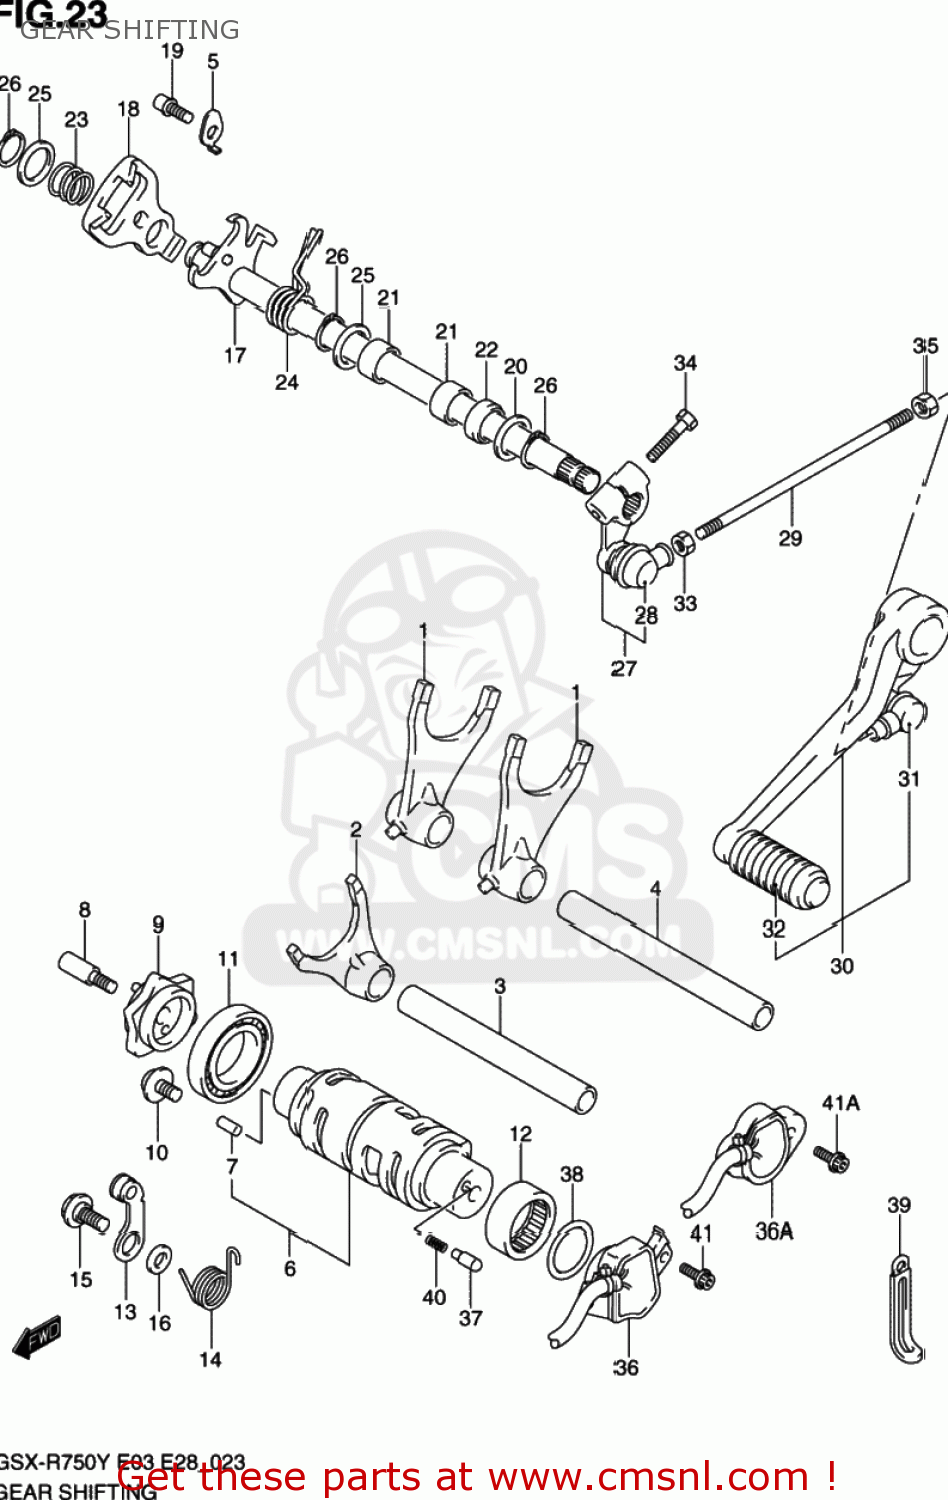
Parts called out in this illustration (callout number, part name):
1	FORK,GEAR SHIFT NO.1
2	FORK,GEAR SHIFT NO.3
3	SHAFT,GEAR SHIFT FORK
4	SHAFT,GEAR SHIFT FORK NO.1
5	RETAINER,GEAR SHIFT FORK SHAFT
6	CAM,GEAR SHIFT
7	PIN
8	BOLT,GEAR SHIFT CAM PL
9	PLATE,GEAR SHIFT CAM
10	SCREW(6X12)
11	BEARING(25X47X8)
12	BEARING(25X32X12)
13	STOPPER,SHIFT CAM
14	SPRING,SHIFT
15	BOLT(6X14.3)
16	WASHER
17	SHAFT,GEAR SHIFT
18	PLATE,GEAR SHIFT CAM DRIVE
19	STOPPER,GEAR SHIFT ARM
20	WASHER(14X29X0.8)
21	BEARING(14X20X12)
22	SEAL,OIL(14X22X6)
23	SPRING
24	SPRING
25	SHIM(14X22X1)
26	CIRCLIP
27	ARM,GEAR SHIFT LINK
28	COVER,DUST
29	ROD,GEAR SHIFT LINK
30	LEVER ASSY,GEAR SHIFT
31	COVER,DUST
32	RUBBER,GEAR SHIFT PEDAL
33	NUT
34	BOLT
35	NUT
36	BASE ASSY,GEAR SHIFT TERMINAL
36A	BASE ASSY,GEAR SHIFT TERMINAL
37	PIN(5X15.5)
38	O RING(D:2.4,ID:25.7)
39	CLAMP(L:65)
40	SPRING
41	BOLT(5X16)
41A	BOLT
